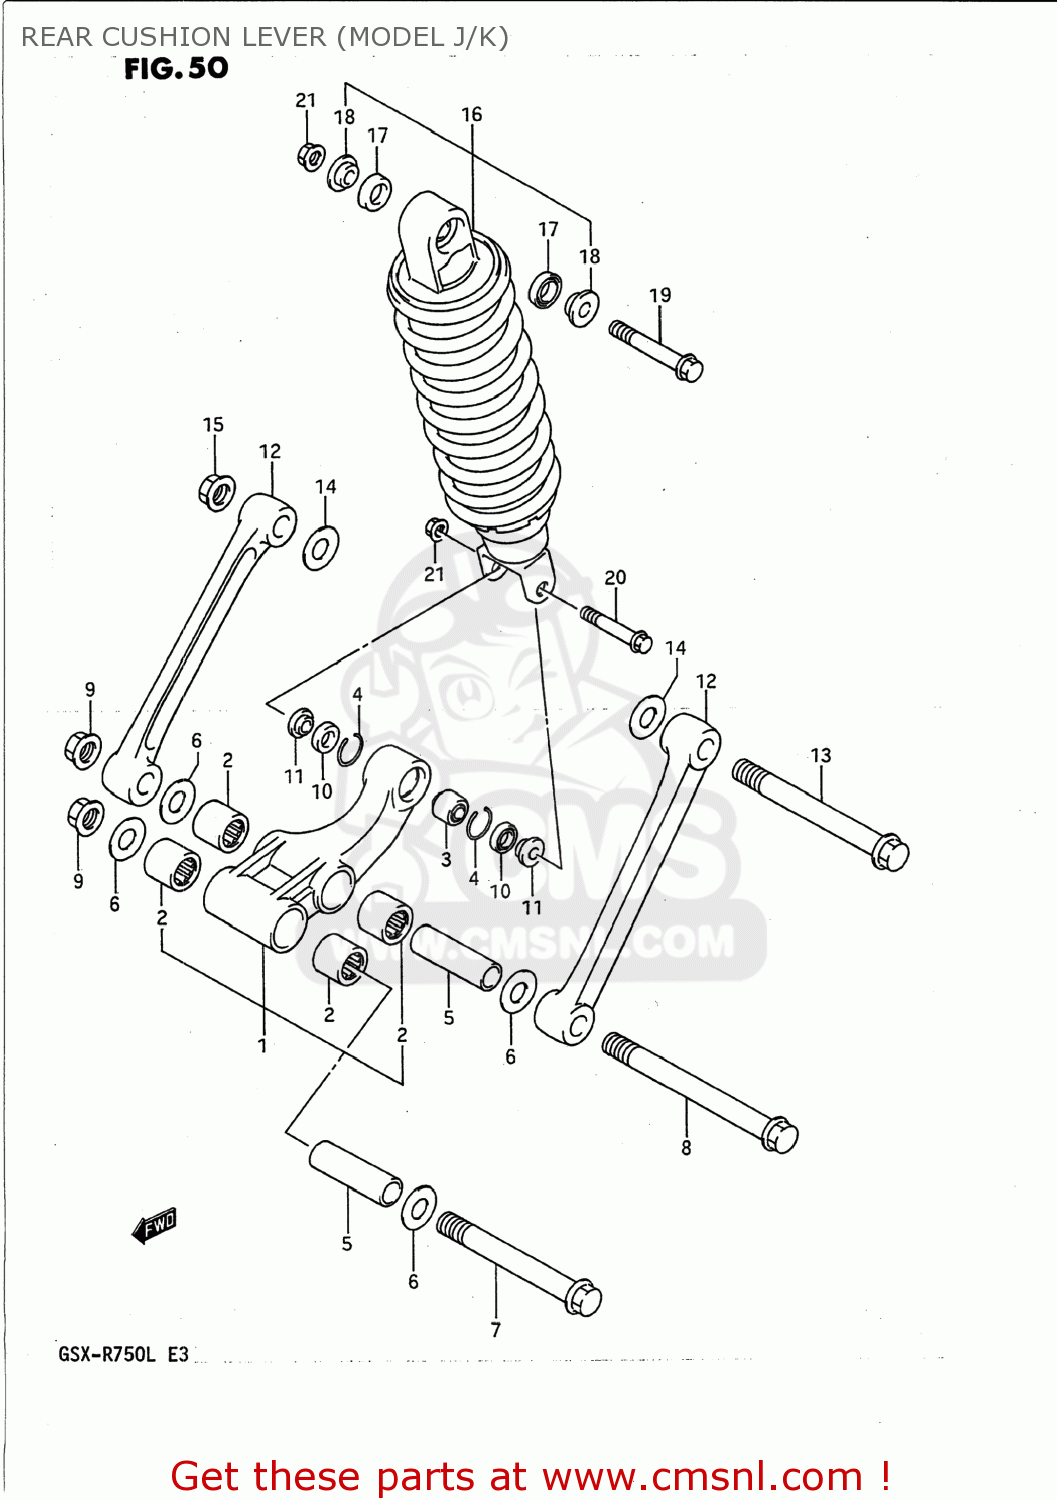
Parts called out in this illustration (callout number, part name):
1	LEVER SET,REAR CUSHION
2	BEARING(20X27X23.5)
3	BEARING,RR CUSHION LEVER
4	RING,STOPPER
5	SPACER,RR CUSHION LEVER
6	WASHER
7	SHAFT,RR CUSHION LEVER FR
8	SHAFT,RR CUSHION ROD
9	NUT
10	DUST SEAL,RR CUSHION LEVER RR
11	SPACER
12	ROD,REAR CUSHION
13	SHAFT,RR CUSHION ROD
14	WASHER
15	NUT
16	ABSORBER ASSY,RR SHOCK
17	DUST SEAL
18	SPACER
19	BOLT
20	BOLT(10X52)
21	NUT
